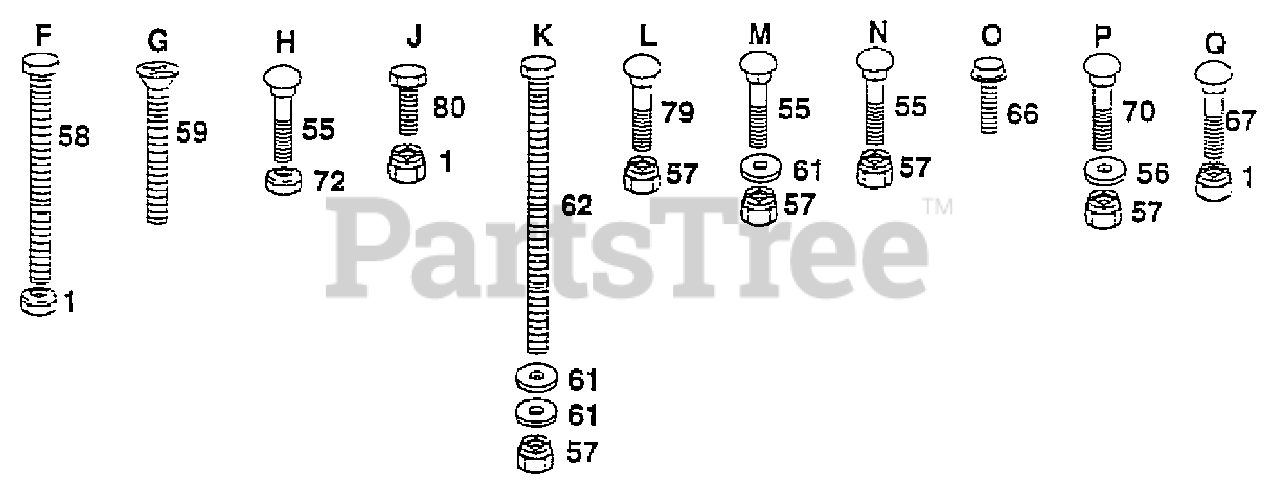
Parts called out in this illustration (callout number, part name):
1	Nut, Crownlock 3/8-16
55	Bolt, Carriage 5/16-18 x 3/4
56	Washer 11/32 x 11/16 x 16 Gauge
57	Nut, Crownlock 5/16-18
58	Bolt, Hex 3/8-16 x 3
59	Screw, Flat Head 3/8-16 x 2
61	Washer 11/32 x 3/4 x 16 Gauge
62	Bolt, Hex -5/16-18 x 5
66	Screw, Hex, Washer Thrdrol. 3/8-16 x 3/4
67	Bolt, Carriage 3/8-16 x 3/4
70	Bolt, Carriage 5/16-18 x 3/4
72	Locknut 5/16-18
79	Bolt, Carriage 5/16-18 x 5/8
80	Bolt, Fin, Hex 3/8-16 x 1
